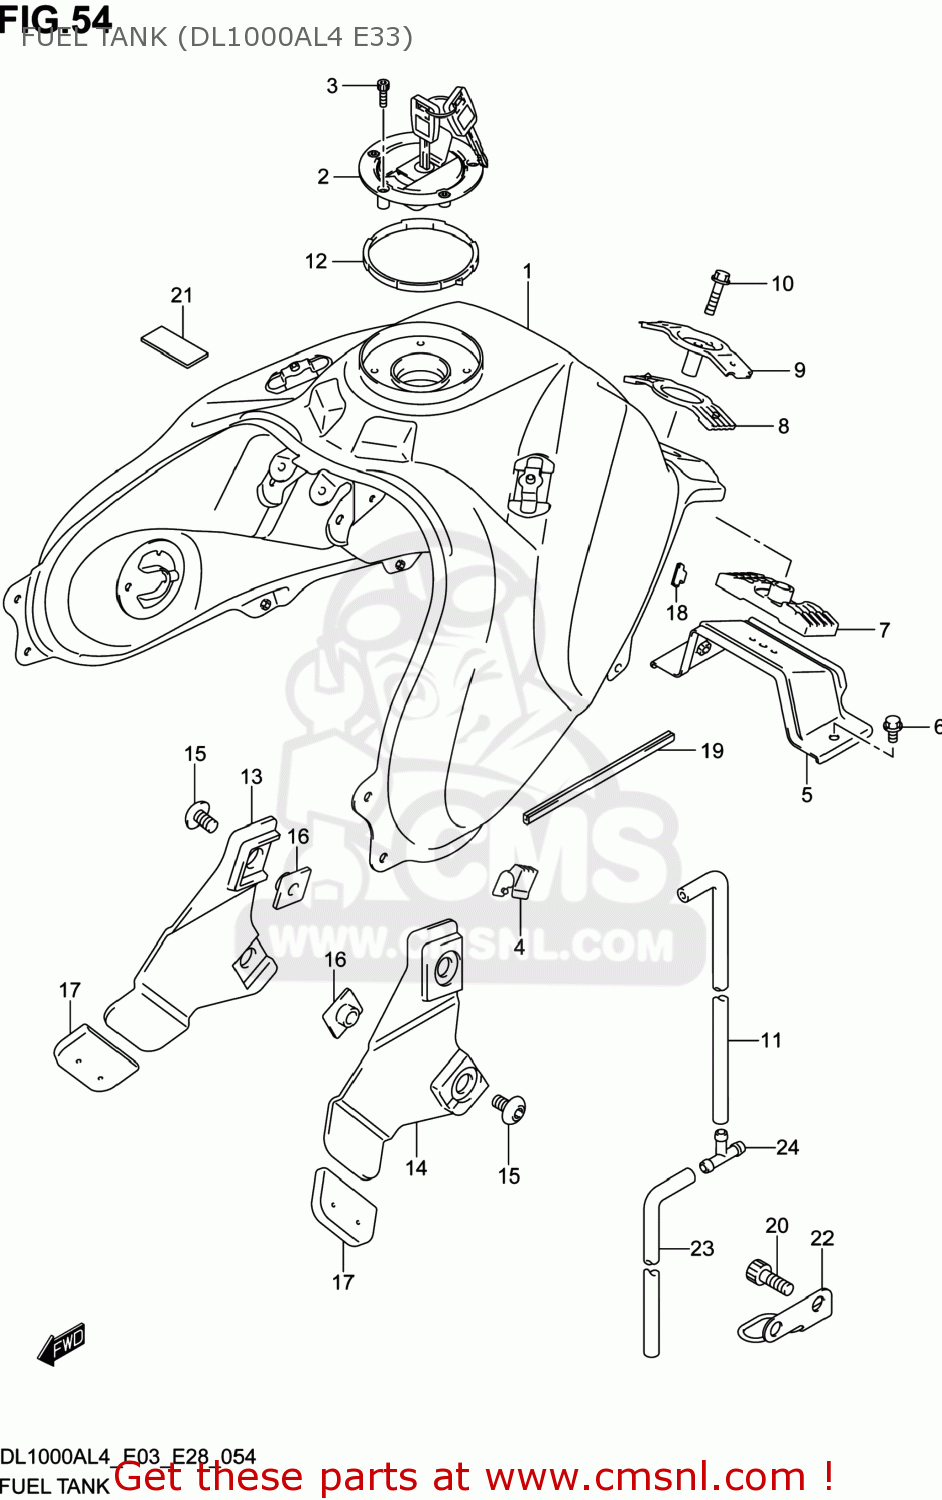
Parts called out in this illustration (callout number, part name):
1	TANK ASSY,FUEL(BLACK)
2	CAP SET,FUEL TANK
3	BOLT,FUEL TANK FILLER CAP
4	CUSHION,FUEL TANK SIDE
5	BRACKET,FUEL TANK REAR
6	BOLT
7	CUSHION,FUEL TANK RR LWR
8	CUSHION,FUEL TANK RR UPR
9	BRACKET,FUEL TANK RR UP
10	BOLT
11	HOSE,FUEL TANK WATER DRAIN
12	MOLDING,FUEL TANK COVER
13	BRACKET,FUEL TANK COVER SIDE,R
14	BRACKET,FUEL TANK COVER SIDE,L
15	SCREW(6X10)
16	NUT(M6)
17	CUSHION,FUEL TANK COVER BRKT
18	CUSHION,FUEL TANK COVER
19	MOLDING,FUEL TANK RR
20	BOLT
21	CUSHION,FUEL TANK
22	GUIDE,DRAIN HOSE
23	HOSE,FUEL TANK DRAIN NO.2
24	3 WAY
